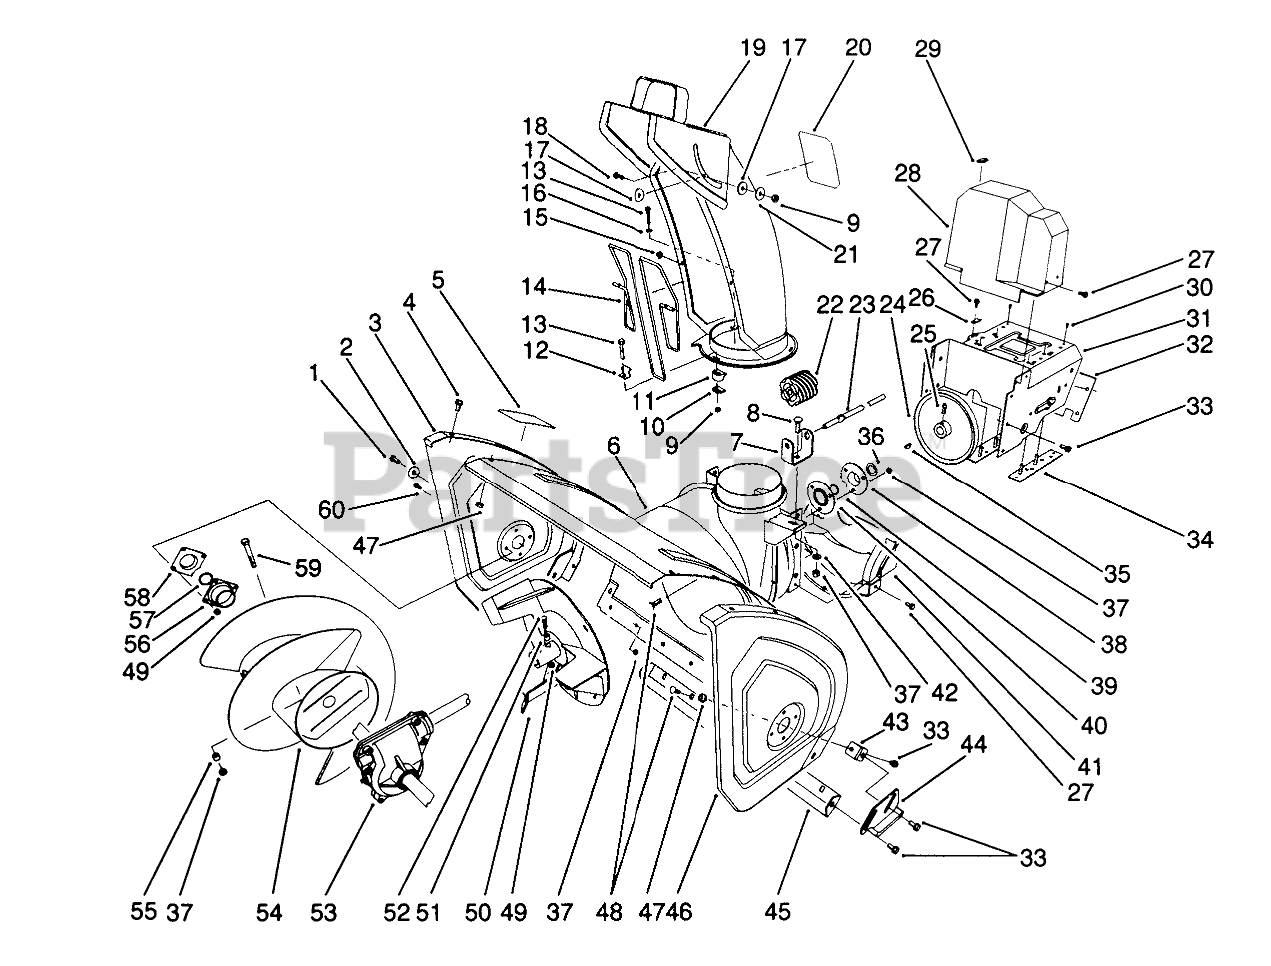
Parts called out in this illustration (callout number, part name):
1	SCREW-HH
2	WASHER
3	PLATE-SIDE, RH
4	SCREW-HHF
5	DECAL-WARNING, AUGER
6	Housing-28"
7	BRACKET-WORM, CHUTE
8	BOLT-CARR
9	NUT-LOCK, NI
10	PLATE-RETAINER, CHUTE
11	RETAINER-CHUTE
12	CLIP-GUARD, CHUTE
13	SCREW-HSH
14	GUARD-CHUTE
15	NUT-PUSH
16	WASHER-FLAT
17	WASHER-PLASTIC
19	Assembly
20	Decal-Danger
21	WASHER-FLAT
22	GEAR-WORM
23	ROD-CHUTE, LOWER
24	PULLEY-IMPELLER
25	SCREW-SET, SQH
26	RETAINER-CABLE
27	SCREW-HWH
28	COVER-BELT, UPPER
29	COVER-CABLE
30	RIVET-POP
31	Frame-Engine
32	Cover-Frame, Engine
33	SCREW-HHF
34	Plate-Ass-y L.H.
35	KEY-WOODRUFF
36	WASHER-THRUST
37	NUT-LOCK, NI
38	Flange-Bearing (Rear)
39	BEARING-BALL
40	Flange-Bearing (Front)
41	Cover-Belt (Lower)
42	WASHER-PLAIN
43	Bracket-Skid
44	SKID WA
45	Blade-Scraper
46	Plate-Side LH
47	NUT-LOCK, NI
48	SCREW-CARR
49	NUT-LOCK, NI
50	Impeller
51	SPACER
52	SCREW-HHF
53	Auger Gearbox Assembly
54	Auger-R.H.
55	SPACER-HUB, AUGER
56	BEARING-FLANGE, FRONT
57	BEARING
58	BEARING-FLANGE, REAR
59	Auger Bolt
60	SCREW-HH
